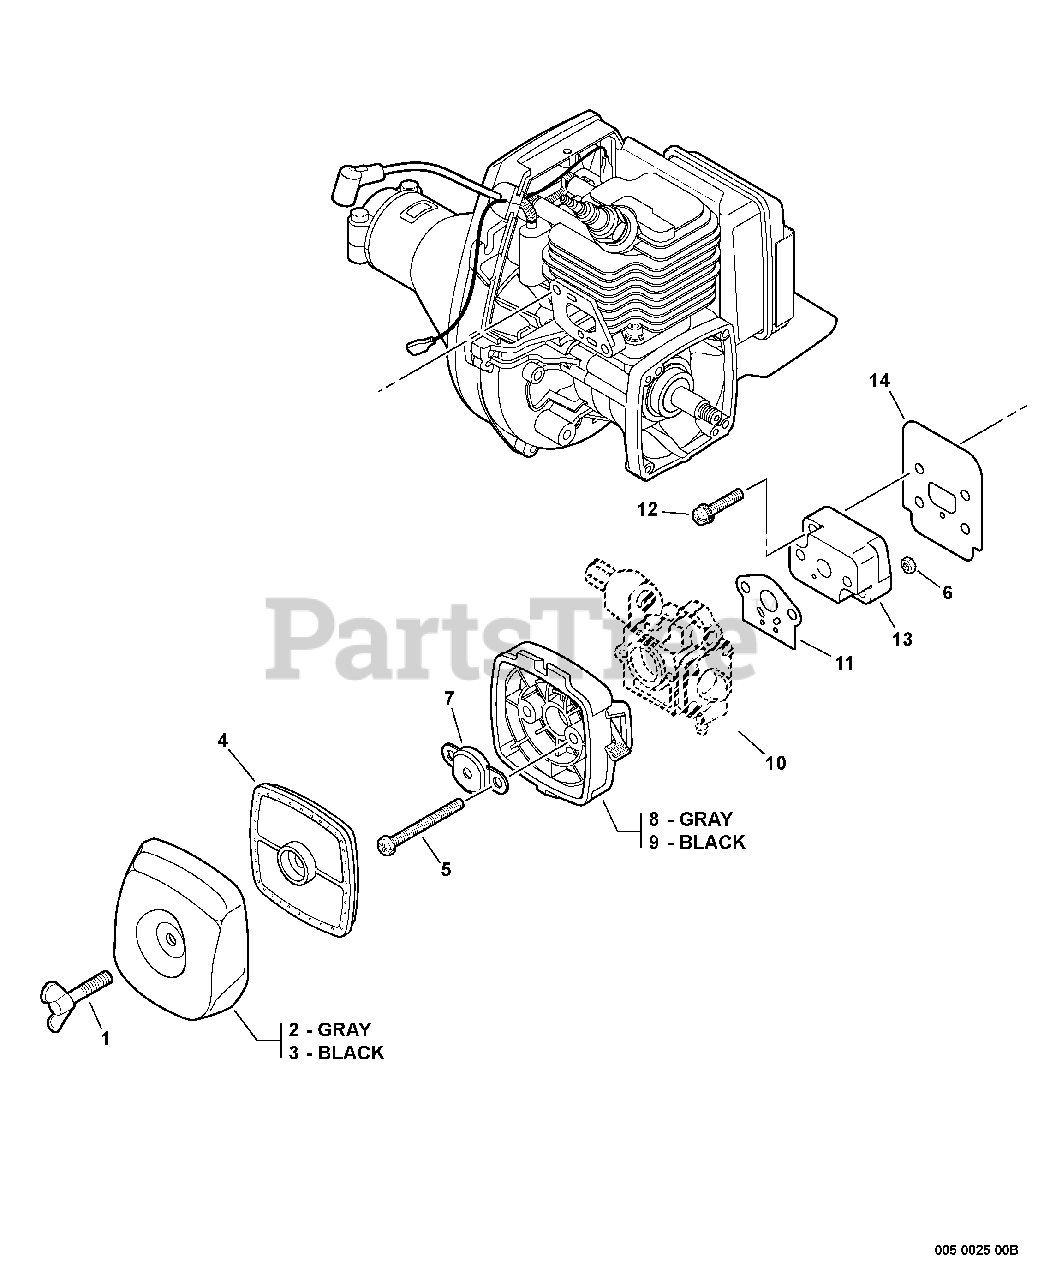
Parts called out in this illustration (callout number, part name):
1	THUMBSCREW
2	COVER, AIR FILTER - GRAY
3	COVER, AIR FILTER - BLACK
4	FILTER, AIR - SINGLE LAYER
5	SCREW - 5X65
7	PLATE, PREVENT
8	CASE, AIR FILTER - GRAY
9	CASE, AIR FILTER - BLACK
10	CARBURETOR
11	GASKET, INTAKE
12	SCREW - 5X20
13	INSULATOR, INTAKE
14	SHIELD, INTAKE
